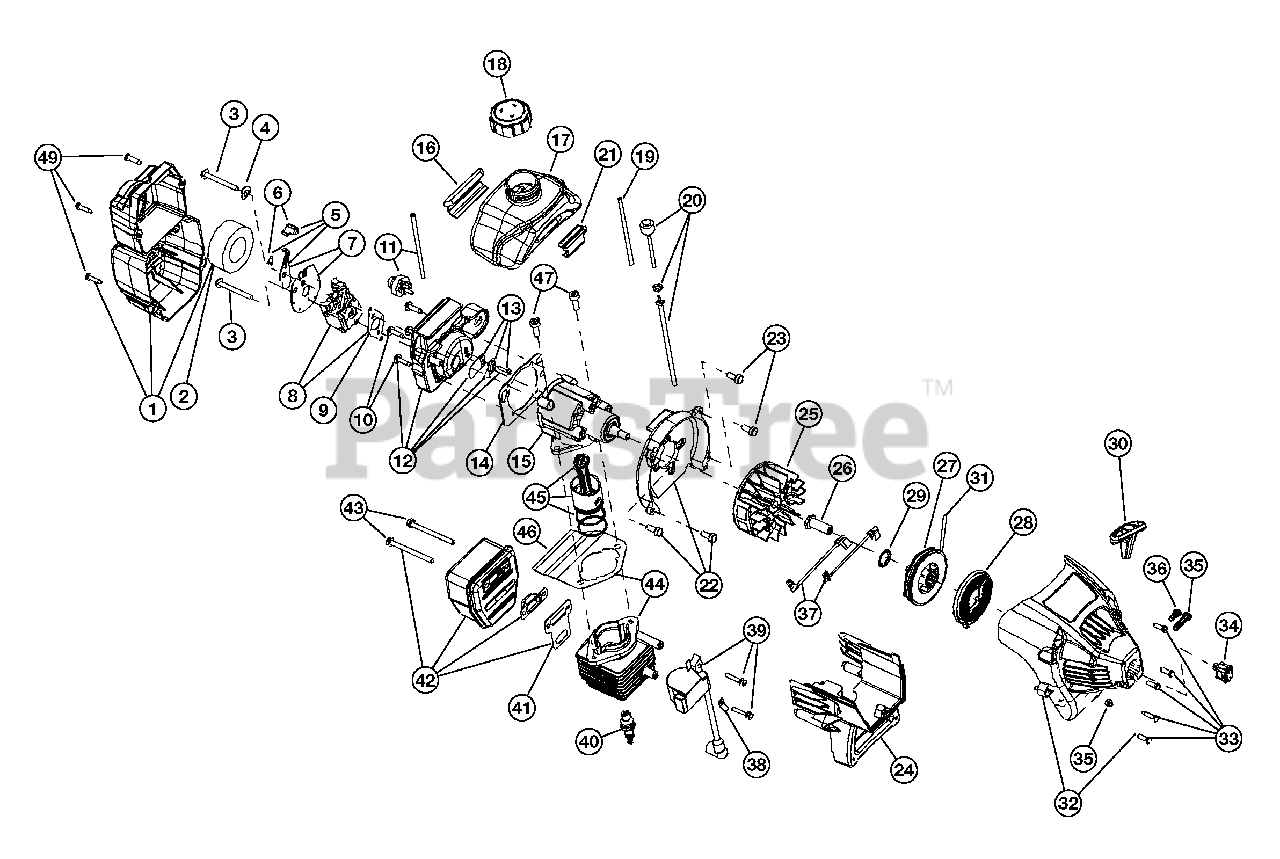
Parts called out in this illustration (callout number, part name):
1	Air Cleaner/Muffler Cover Assembly
2	Air Cleaner Filter
3	Carburetor Mounting Screws
4	Wavey Washer
5	Choke Lever Assembly
6	Choke Knob and Screw
7	Choke Lever and Plate
8	Carburetor Assembly
9	Carburetor Gasket
10	Carb Mount Screw
11	Primer and Hose Assembly
12	Carb Mount Assembly
13	Reed Assembly
14	Carburetor Mount Gasket
15	Crank Case Service Assembly
16	Rear Mounting Pad
17	Fuel Tank Assembly
18	Fuel Cap Assembly
19	Fuel Return Line
20	Fuel Line Assembly
21	Front Mounting Pad
22	Shroud Assembly
23	Shroud Screw
24	Shroud Extension and Stand
25	Flywheel Assembly
27	Recoil Pulley
28	Recoil Spring
29	Pulley Retainer
30	Pull Handle
32	Starter Housing Assembly
33	Housing Screws
34	On/Off Switch
35	Clamping Screw & Nut
36	Anti-Rotation Screw
37	Wire Leads
38	Ground Tab
39	Module Assembly
40	Spark Plug
41	Exhaust Gasket
42	Muffler Assembly
43	Muffler Mounting Bolt
44	Cylinder Assembly
45	Piston and Rod Assembly w/Rings
46	Cylinder Gasket
47	Cylinder Bolt
48	Spark Arrestor Screen
49	Cover Screws
